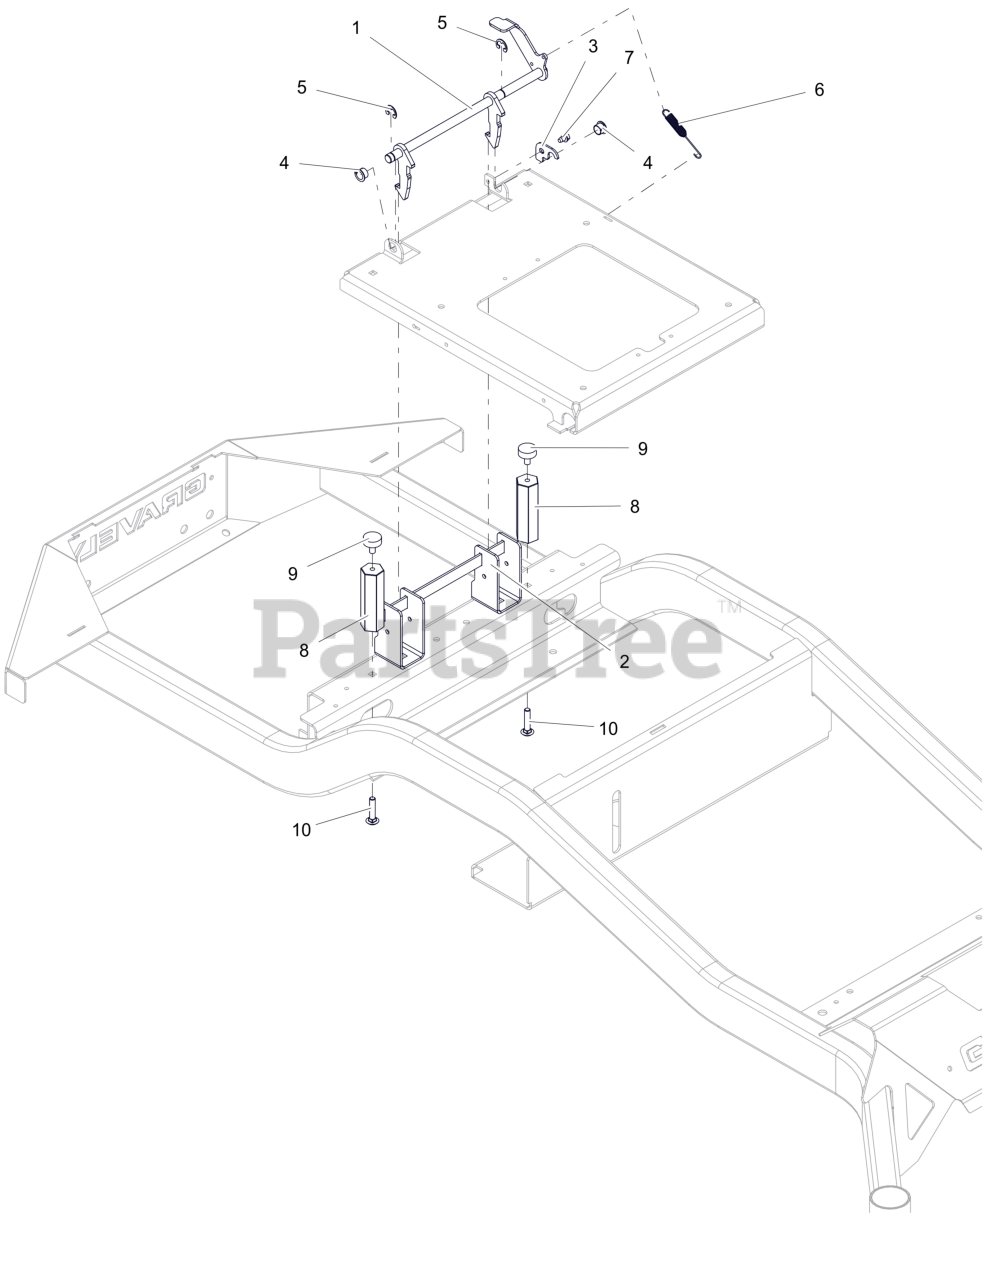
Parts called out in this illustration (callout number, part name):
1	WLDMT, SEAT LATCH (BLACK)
2	WLDMT, LATCH RECEIVER
3	BRKT, ROD KEEPER (BLACK)
4	BUSHING, POLYLINER-.50 SPLIT
5	RG-RTNG-EXT .500X.042 (E)
6	SG-TENS .043X.44X3.31 WLD 5.8
7	SCR,TAP .25-20X.375 HWH TR ZCC
8	NUT, COUPLER 5/16-18 X 1.125X 3.8
9	BUMPER, RUBBER
10	BLT,RHSN .31-18X1.50 G5 ZCC
